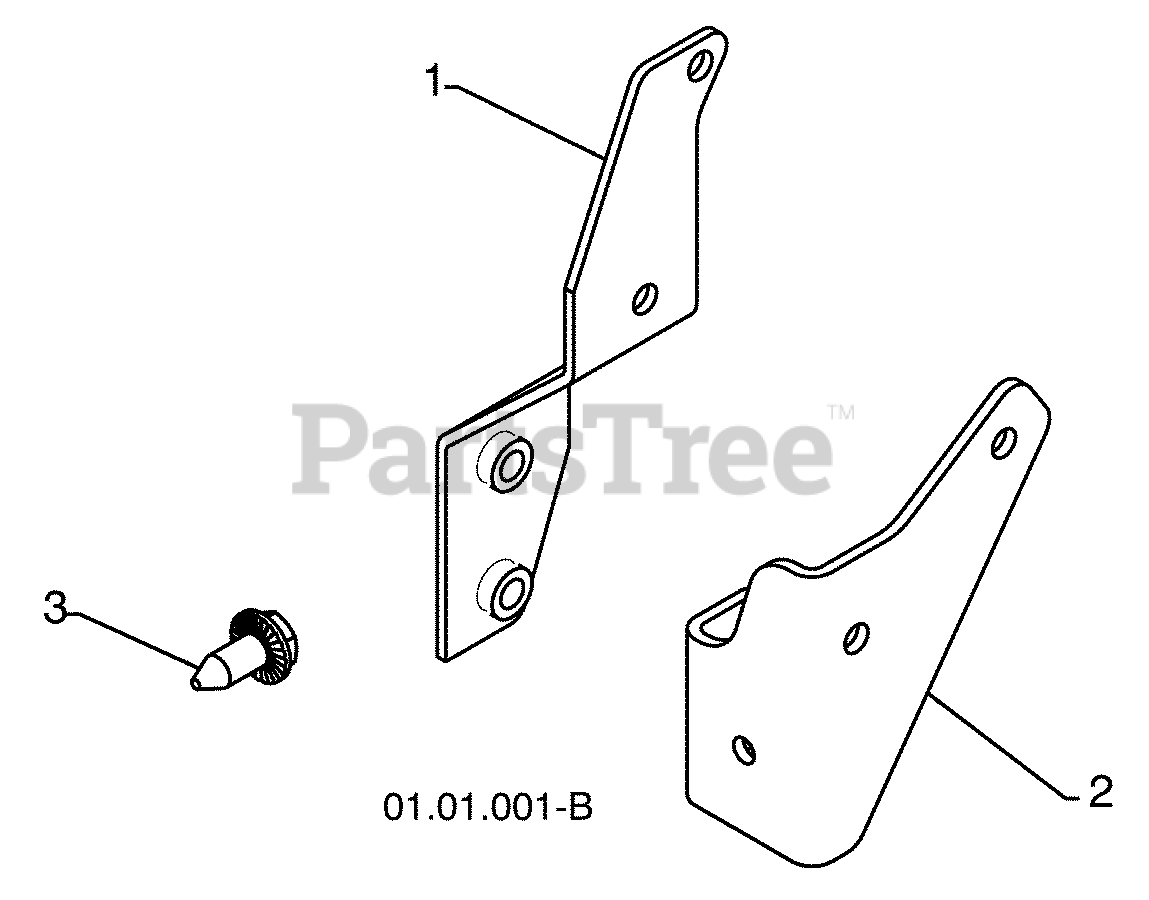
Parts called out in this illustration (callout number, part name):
1	TORQUE STRAP
2	ANTI ROTATE BRACKET
3	SCREW 5/16-18 X .750
